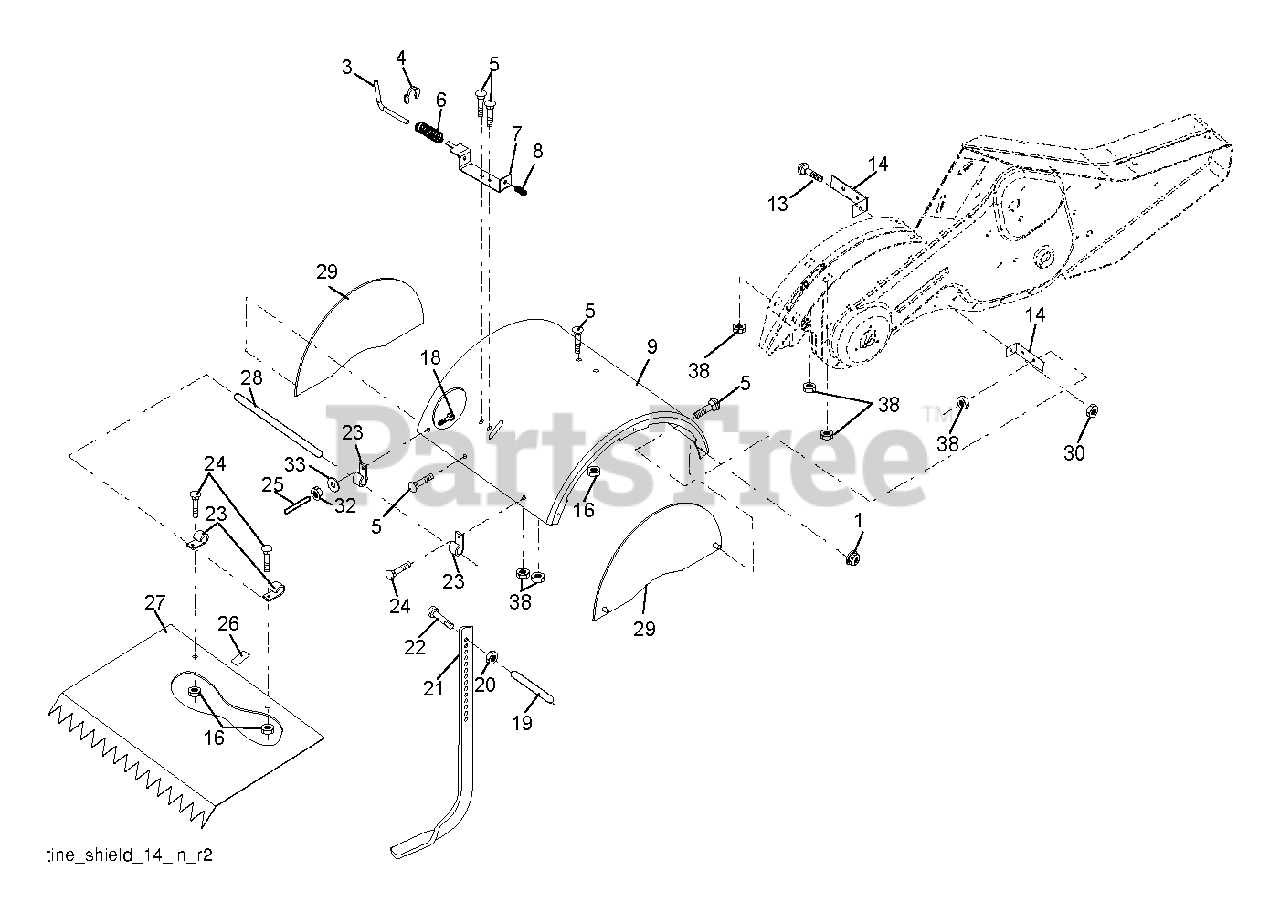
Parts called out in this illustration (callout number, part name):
1	NUT LOCK HEX FLANGE 5/16-18
3	STAKE PIN TI
4	RING, KLIP
5	BOLT, RDHD SQNK 5/16-18 X 3/4
6	SPRING TI
7	LATCH BRACKET TI
8	SPRING CRT
13	BOLT.CARRIAGE.5/16-18
14	BRACKET.TINE.SHIELD.TILLER.BLA
16	NUT T
19	GRIP CRT
20	NUT.HEX.3/8-16UNC
21	STAKE.DEPTH.16.CRT.BLACK
22	BOLT.375-16
23	HINGE CRT
26	PAD IDLER TI
27	SHIELD.TILLER.LEVELING.YELLOW
28	PIN.HINGE.TILLER
29	SHIELD.ASM.TILLER.SIDE.YELLOW
30	LOCKNUT-FLANGE 5/16-18
32	NUT
33	LOCKWASHER
